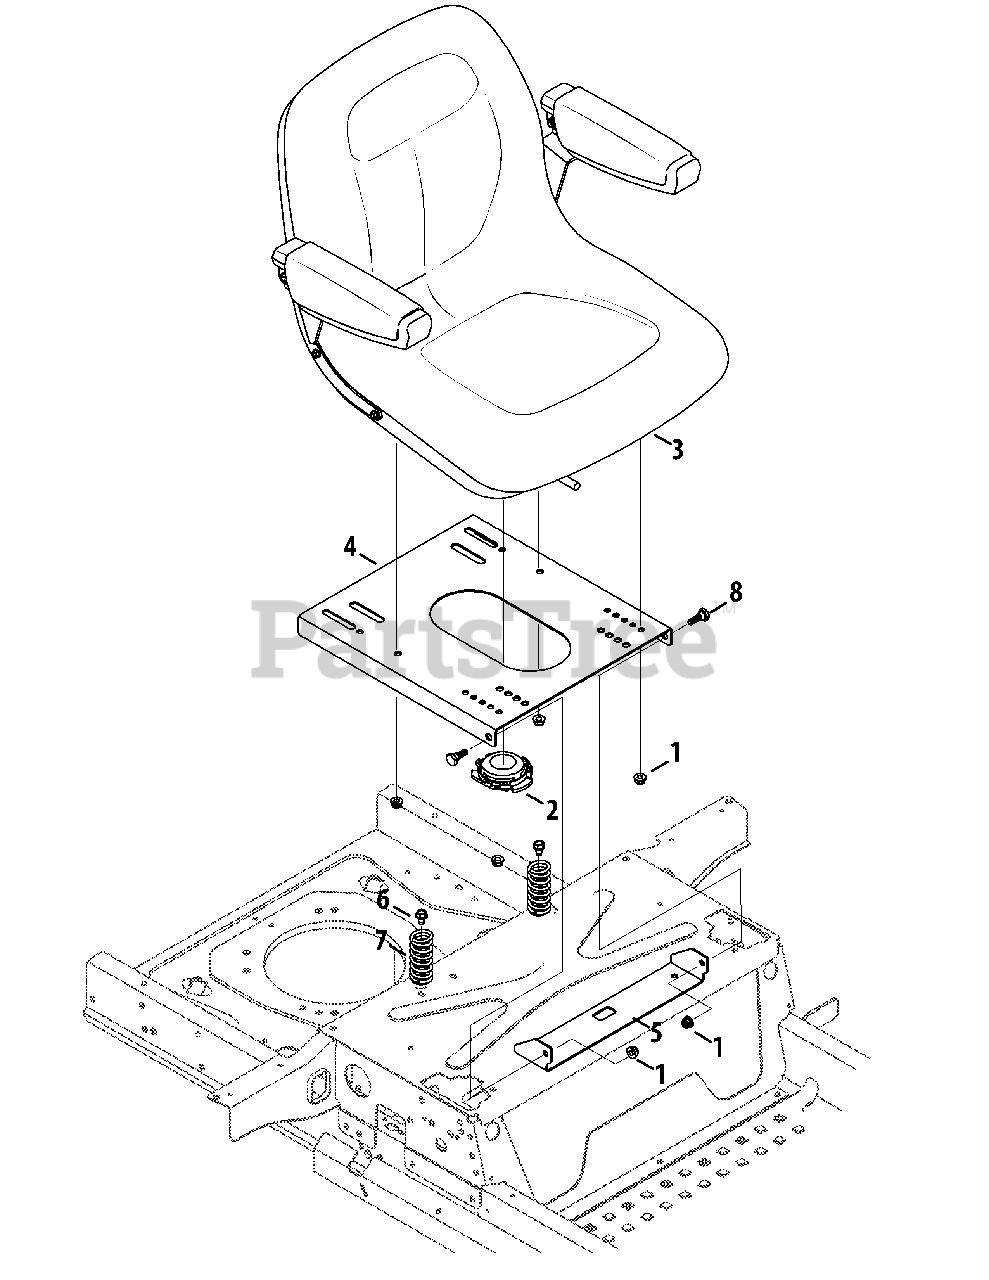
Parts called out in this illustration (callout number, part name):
1	Flange Lock Nut, 5/16-18
2	Seat Switch
4	Seat Plate
6	Hex Washer Screw, 5/16-18 x .750
7	Compression Spring, 1.71 x 3.25 x .23
8	Shoulder Screw, 5/16-18 x .437 x .268
